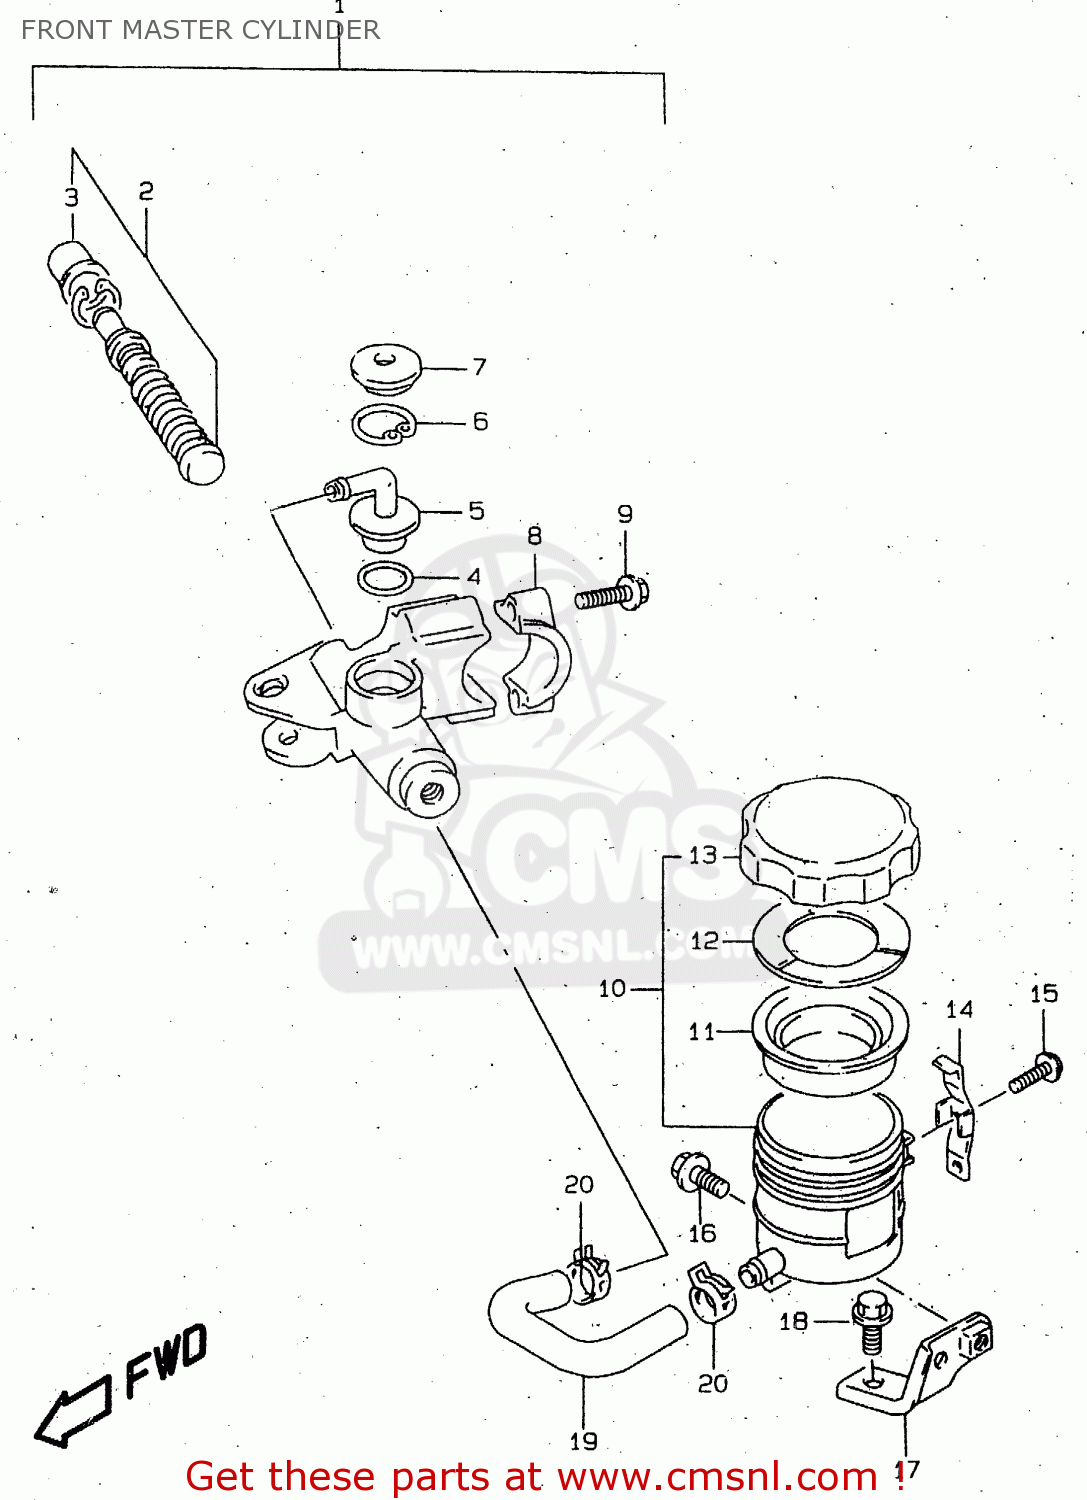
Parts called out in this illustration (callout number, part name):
1	CYLINDER ASSY,FR MASTER
2	PISTON & CUP SET
3	BOOT
4	O RING
5	CONNECTOR
6	CIRCLIP
7	COVER,DUST
8	HOLDER
9	BOLT(6X25)
10	TANK ASSY,RESERVOIR
11	DIAPHRAGM
12	PLATE,DIAPHRAGM
13	CAP
14	PLATE,RESERVOIR TANK CAP
15	SCREW
16	BOLT
17	BRACKET,RESERVOIR TANK
18	BOLT
19	HOSE,RESERVOIR TANK FR
20	CLAMP,RESERVOIR TANK FR
